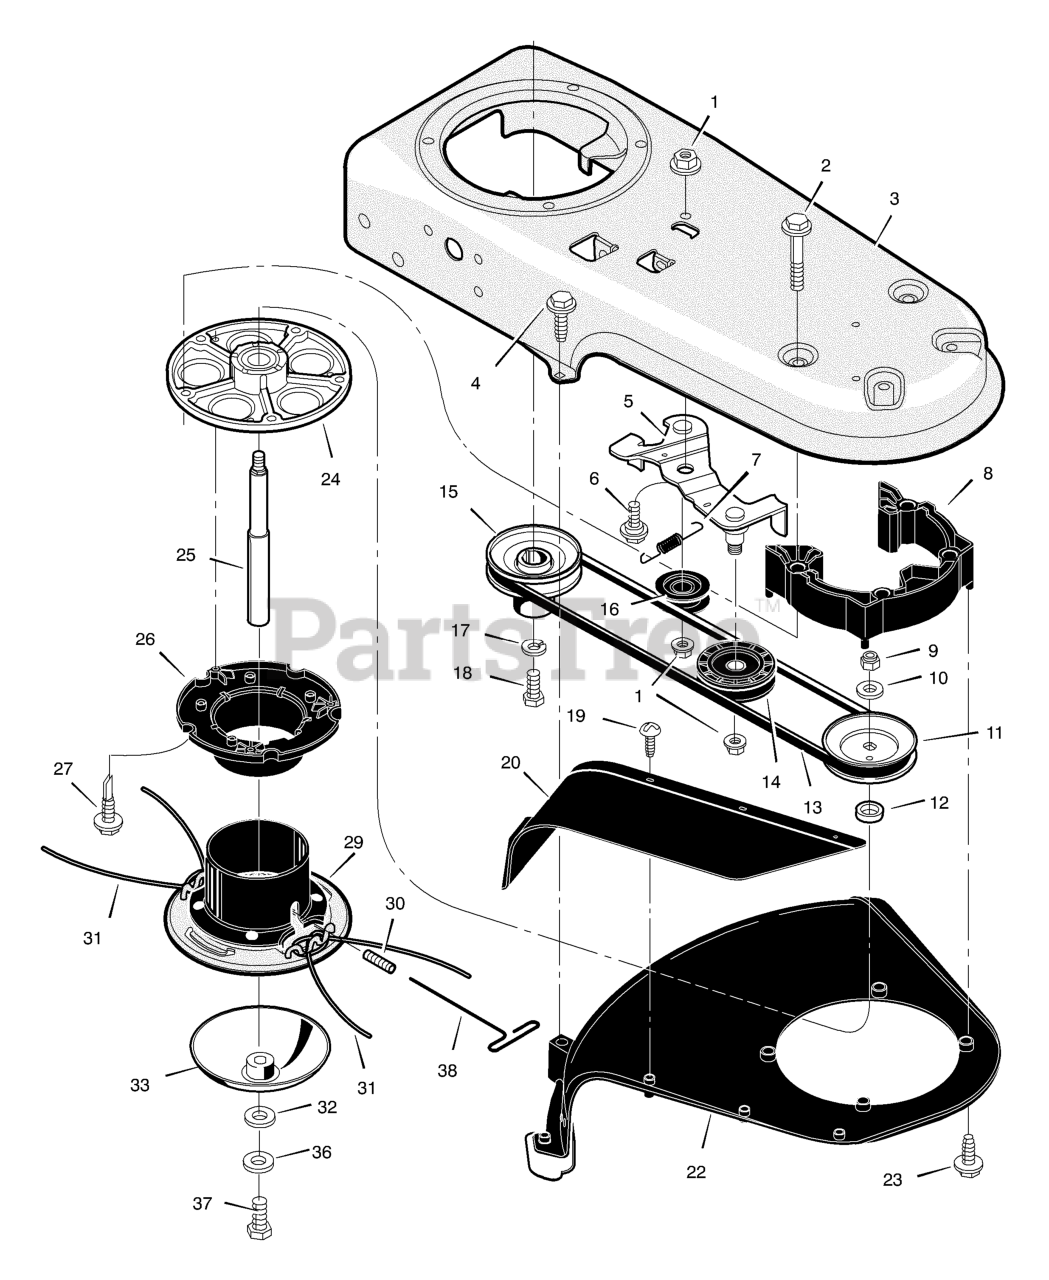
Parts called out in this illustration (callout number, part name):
1	Nut
5	Bracket, Idler Assembly
7	Spring, Extension
8	Spacer Assembly, Jackshaft
10	Washer, Flat
11	Pulley, Cutting Head
12	Spacer, Upper Pulley
13	Belt, Trimmer
14	PULLEY, IDLER, V, 1.88
15	Pulley, Engine
16	Pulley, Idler
17	Lockwasher
20	Flap, Debris
22	Shield, Trimmer
24	Housing, Jackshaft
25	Shaft, Cutting Head
26	Wrap, Weed
29	Assembly, Cutter Head & Wrap
30	Screw, Set
31	Line, Trimmer 0.155 X 21.25
32	Flatwasher
33	Guide, Metal Height
36	Lockwasher
38	Wrench, T-Handle
